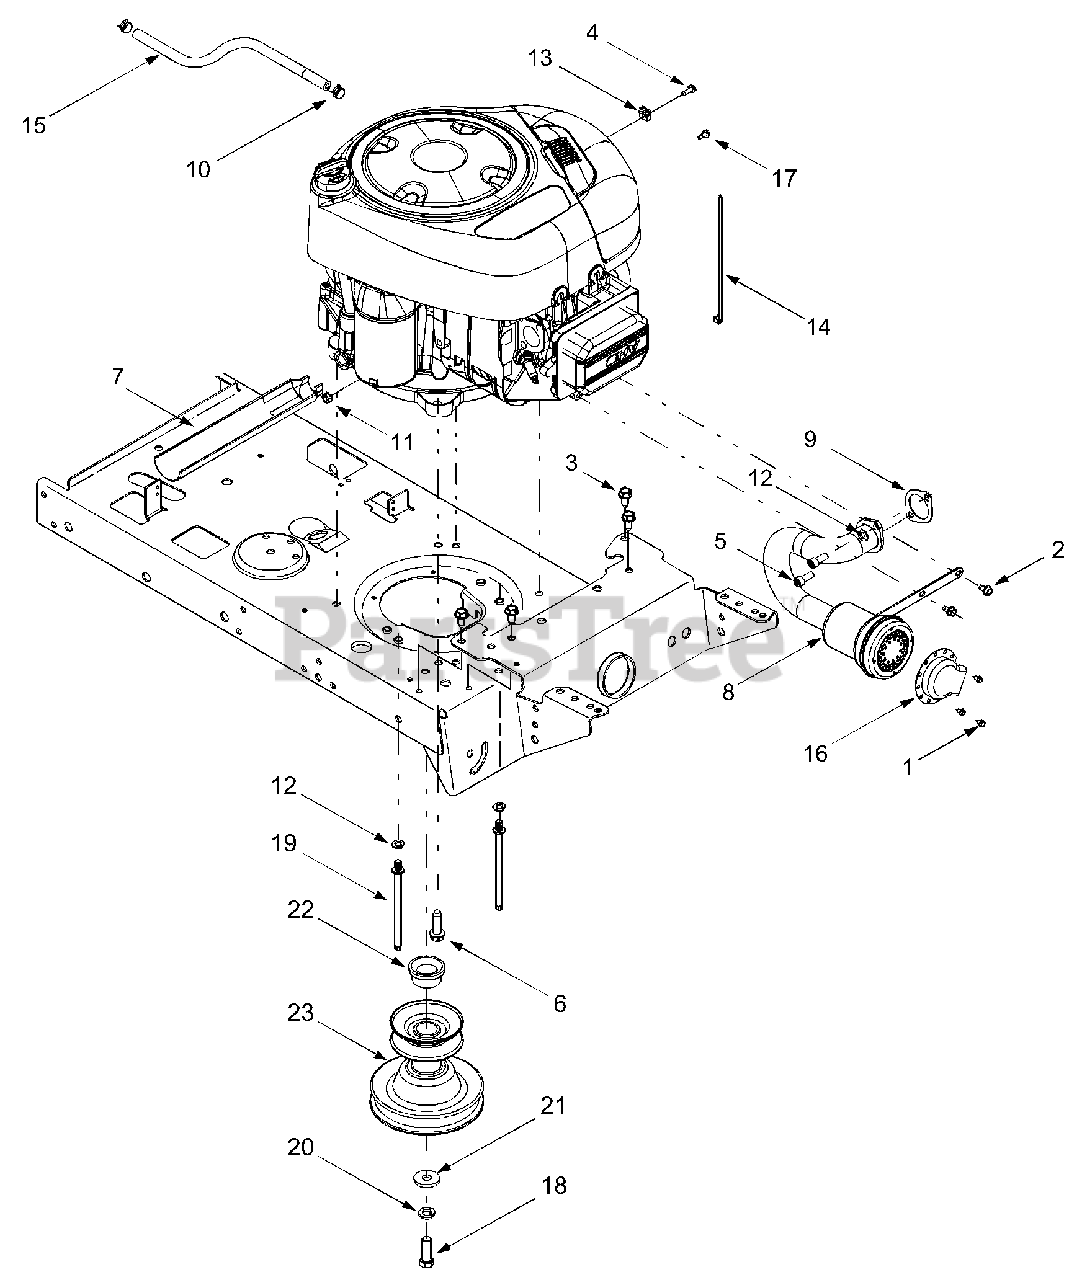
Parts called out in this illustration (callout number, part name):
1	Screw, #8-18 x .375
2	Self-tapping Screw, 1/4-20 x .5
3	Self-tapping Screw, 5/16-12 x .75
4	Screw, #10-32 x .625
5	Socket Cap Screw, 5/16-18 x .625
6	Self-tapping Screw, 3/8-16 x 1.25
7	Oil Drain Sleeve
8	Muffer, Single Inlet
9	Exhaust Gasket
10	Hose Clamp, .490
11	Hex Sems Nut, 1/4-20
12	Lock Washer, 5/16
13	Casing Clamp
14	Cable Tie
15	Fuel Line Hose
16	Muffler Deflector
17	Screw, #10-16 x .5
18	Hex Screw, 7/16-20 x 1.25
19	Belt Keeper Pin, 5/16 x 4.75
20	Lock Washer, 7/16
21	Flat Washer, .450 x 1.25 x .164
22	Spacer, 1.0 x 1.4 x .825
23	Engine Pulley, 3.12 x 5.56
